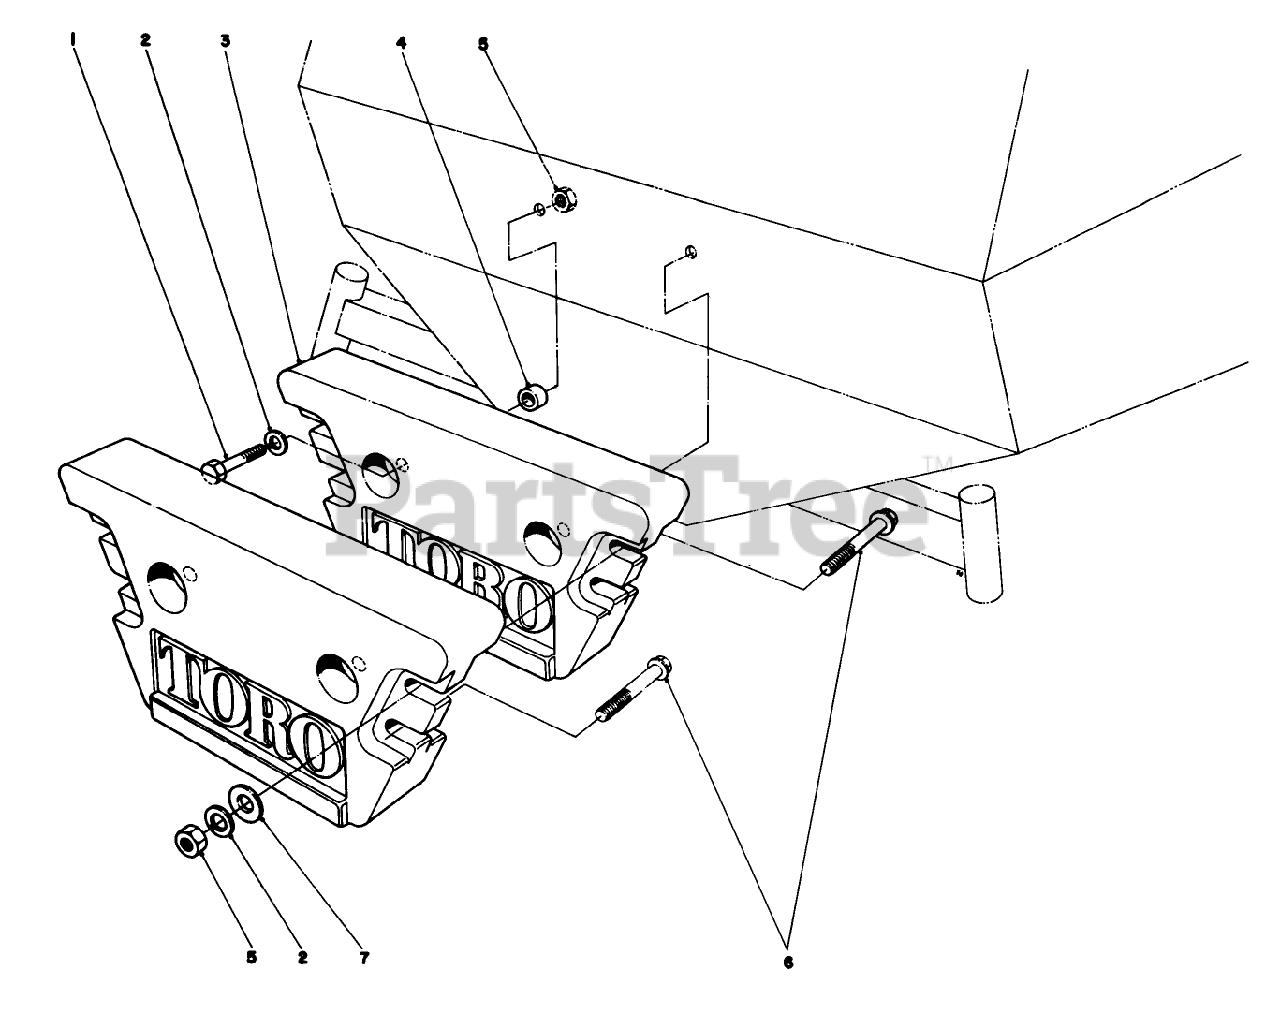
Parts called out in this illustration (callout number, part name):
1	SCREW-HH
2	WASHER-LOCK
3	WEIGHT-REAR
4	SPRING ANCHOR BSHG
5	NUT-HH
6	SCREW-HH
7	WASHER-FLAT
